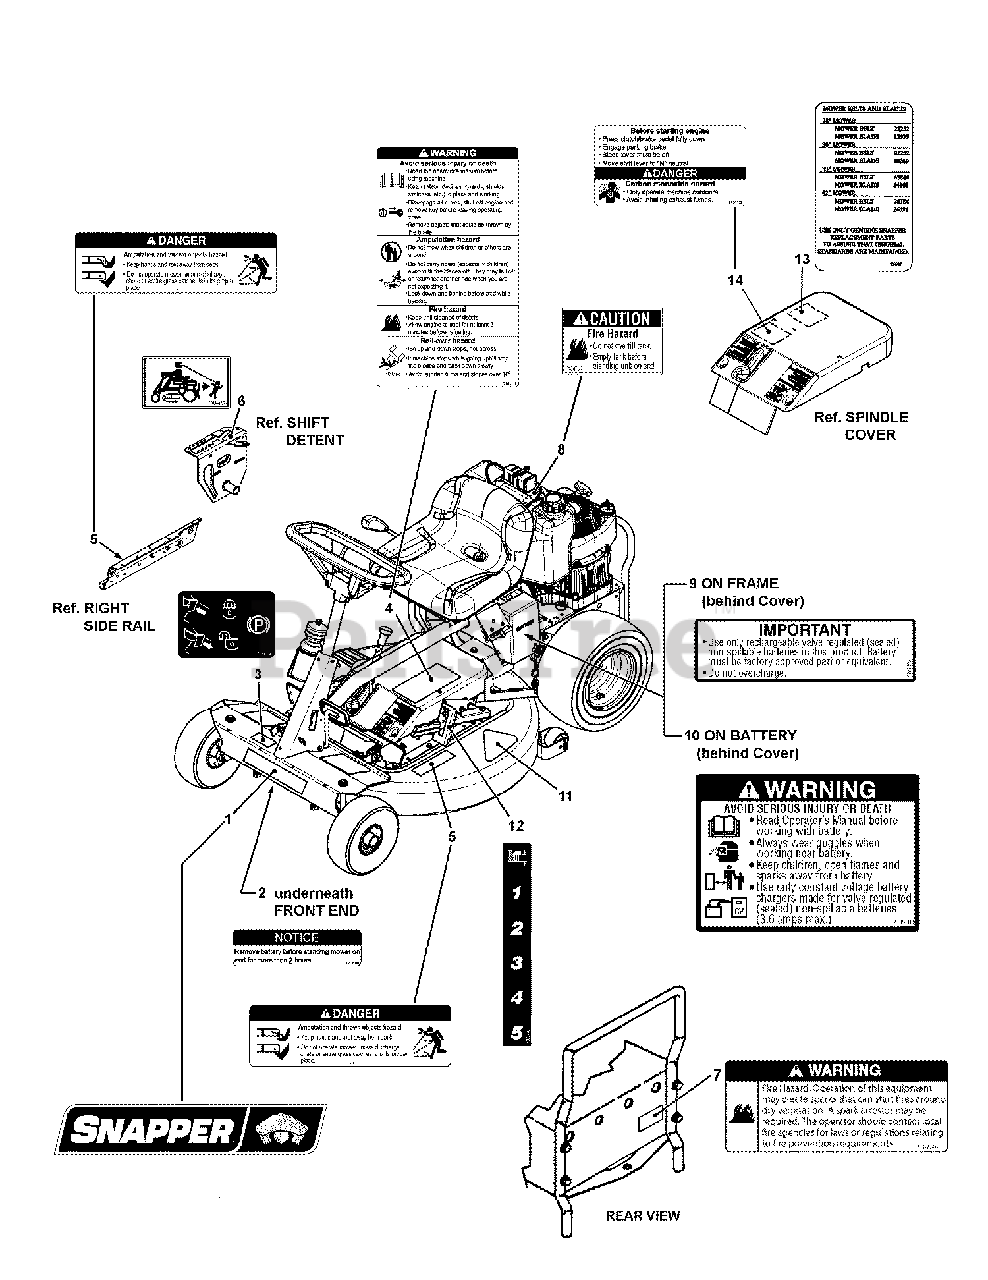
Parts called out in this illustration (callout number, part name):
1	DECAL, Snapper, Turtle Lockup
2	DECAL, Battery, MY07.5
3	DECAL, ID, Parking Lock
4	DECAL, Safety Panel, Warning, MY07.5
5	DECAL, Danger, Deck, MY07.5
6	DECAL, Reverse Lockout, RER
7	DECAL, Spark Arrestor
8	DECAL, Caution, Fuel Tank, RER
9	DECAL, Important, Battery, Non-Spillable
10	DECAL, Warning, Non-Spillable Battery
11	DECAL, 28" Deck
11	DECAL, 30" Deck
11	DECAL, 33" Deck
12	DECAL, Height-Of-Cut, Symbol, RER
13	DECAL, Service Parts, RER, Domestic
14	DECAL, Safety, Panel, Danger, MY07.5
